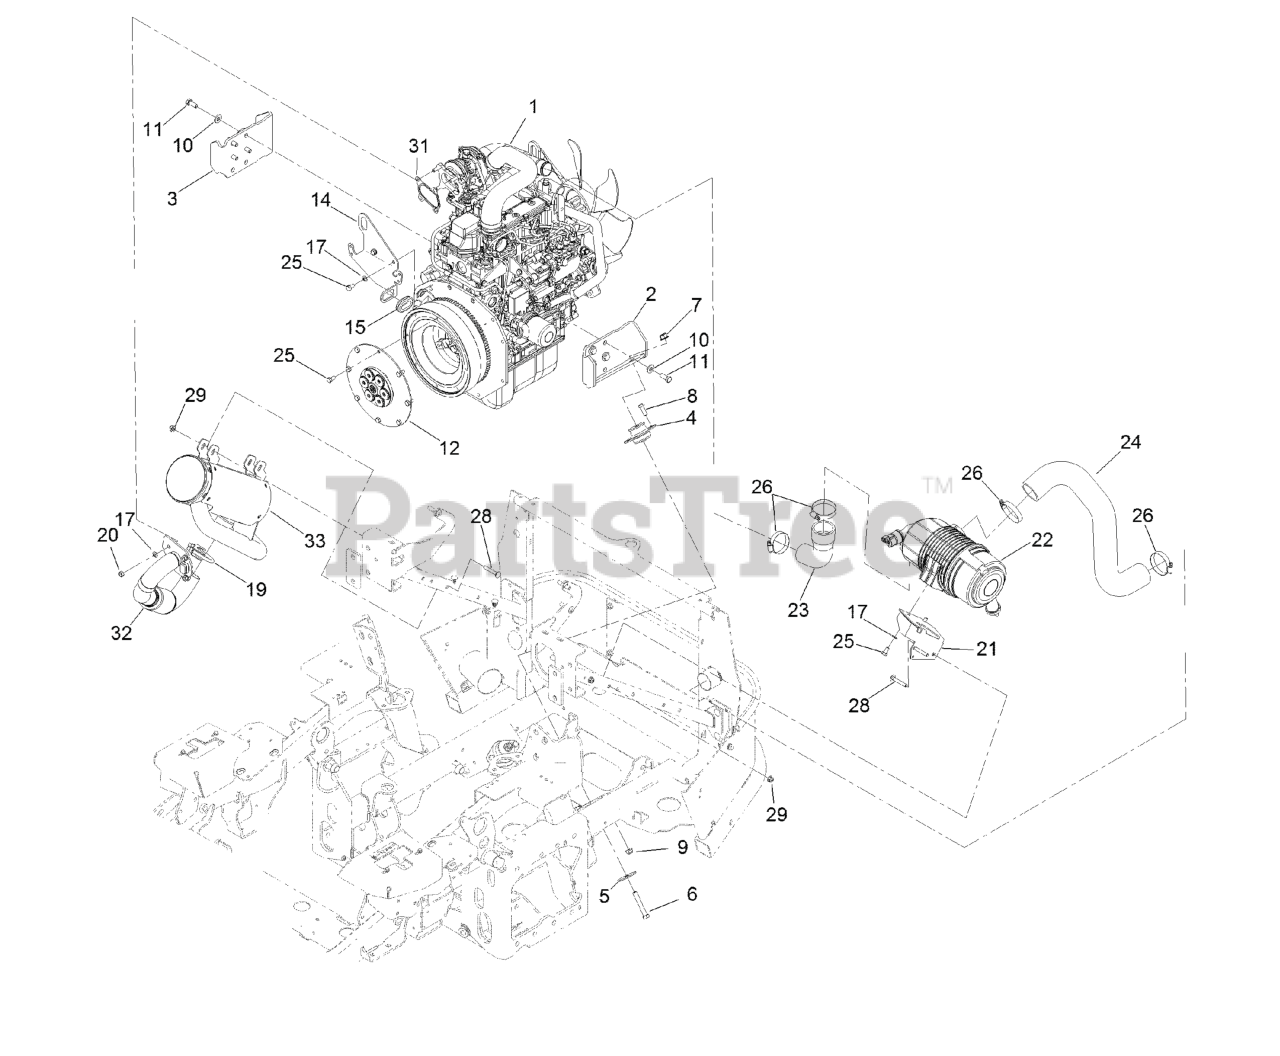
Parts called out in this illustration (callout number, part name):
1	Engine,Yanmar 3Tnv80Ft-Zmtr1
2	MOUNT-ENGINE, LH
3	MOUNT-ENGINE, RH
5	WASHER-SNUBBING
6	SCREW-HH
7	NUT-HF, NI
8	SCREW-HH
9	NUT-HF, NI
10	WASHER-BELLEVILLE
11	SCREW-HH
12	Flywheel Coupling ASM
14	BRACKET-GUIDE
15	GROMMET
17	WASHER-BELLEVILLE
20	NUT-HEX
21	BRACKET-CLEANER, AIR
22	AIR CLEANER ASM
23	HOSE-AIR
24	HOSE-AIR
25	BOLT
26	CLAMP-HOSE
28	BOLT-CARR
29	NUT-HF, NI
31	GASKET-HEADER
32	HEADER PIPE
33	MUFFLER
